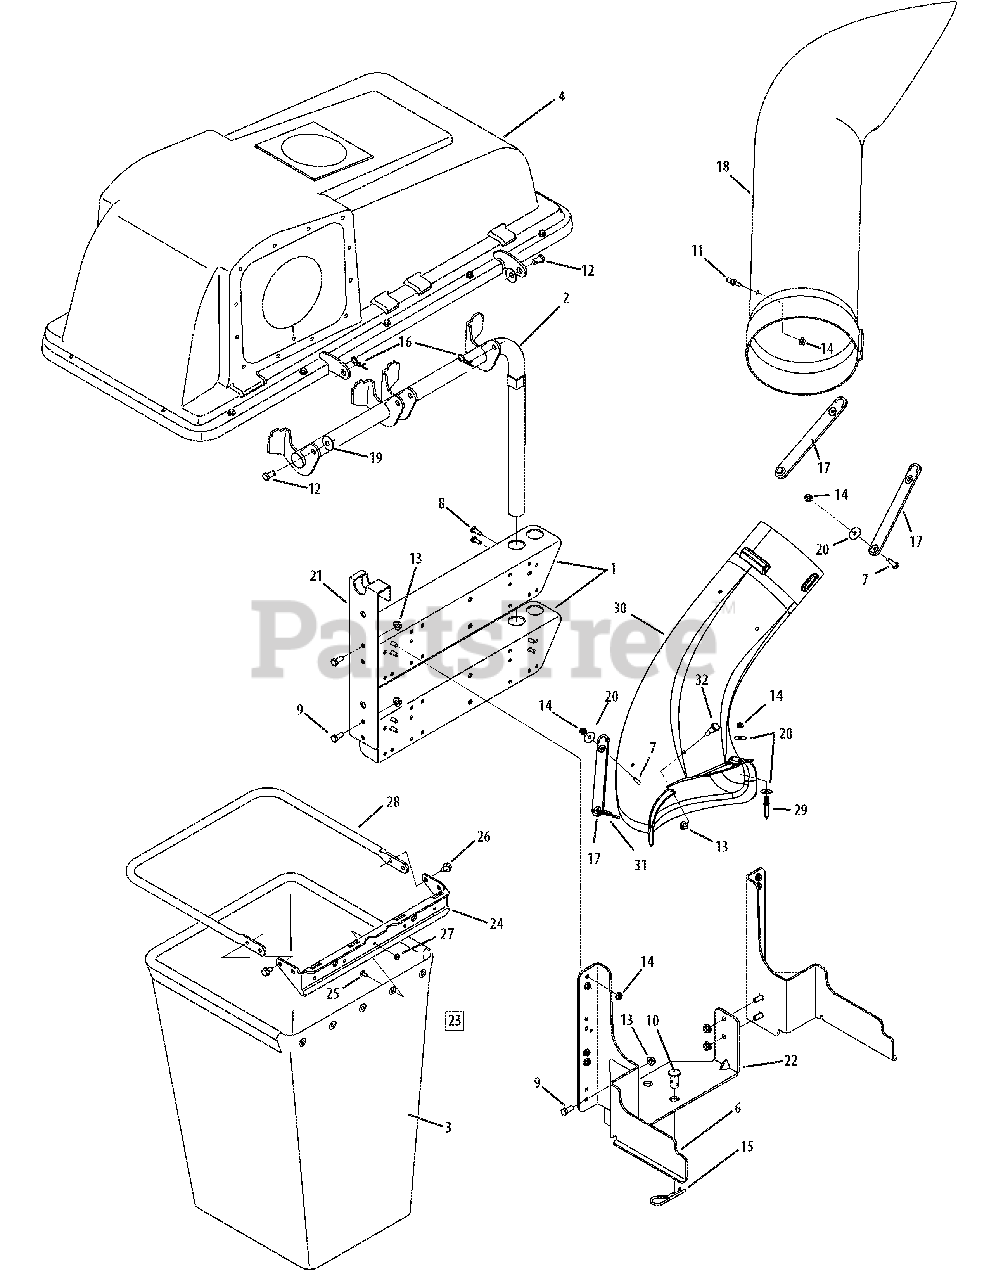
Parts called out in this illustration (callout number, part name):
3	Catcher Bag
4	Grass catcher Cover Assembly
7	Screw 1/4-20 x 1"
8	Hex Screw 1/4-20 x0.620
9	Hex Screw 5/16-18 x 0.75"
10	Clevis Pin
11	Grass catcher Pin
12	Clevis Pin
13	Flange Lock Nut, 5/16-18
14	Flange Lock Nut, 1/4-20
15	Hairpin Clip
16	Click Pin
17	Chute Strap - 6"
18	Catcher Tube
19	Bell Washer
20	Flat Washer
23	Grass Bag Assy.
25	Machine Screw, #10-24 x .5
26	Self-Tapping Screw 5/16-18
27	Hex Sems Nut, #10-24
29	Belt Pin Guard, 1/4 x 1.43
30	Chute Elbow, 42" Timing Deck
31	Spring Hook
32	Shoulder Screw, .437 x .54
